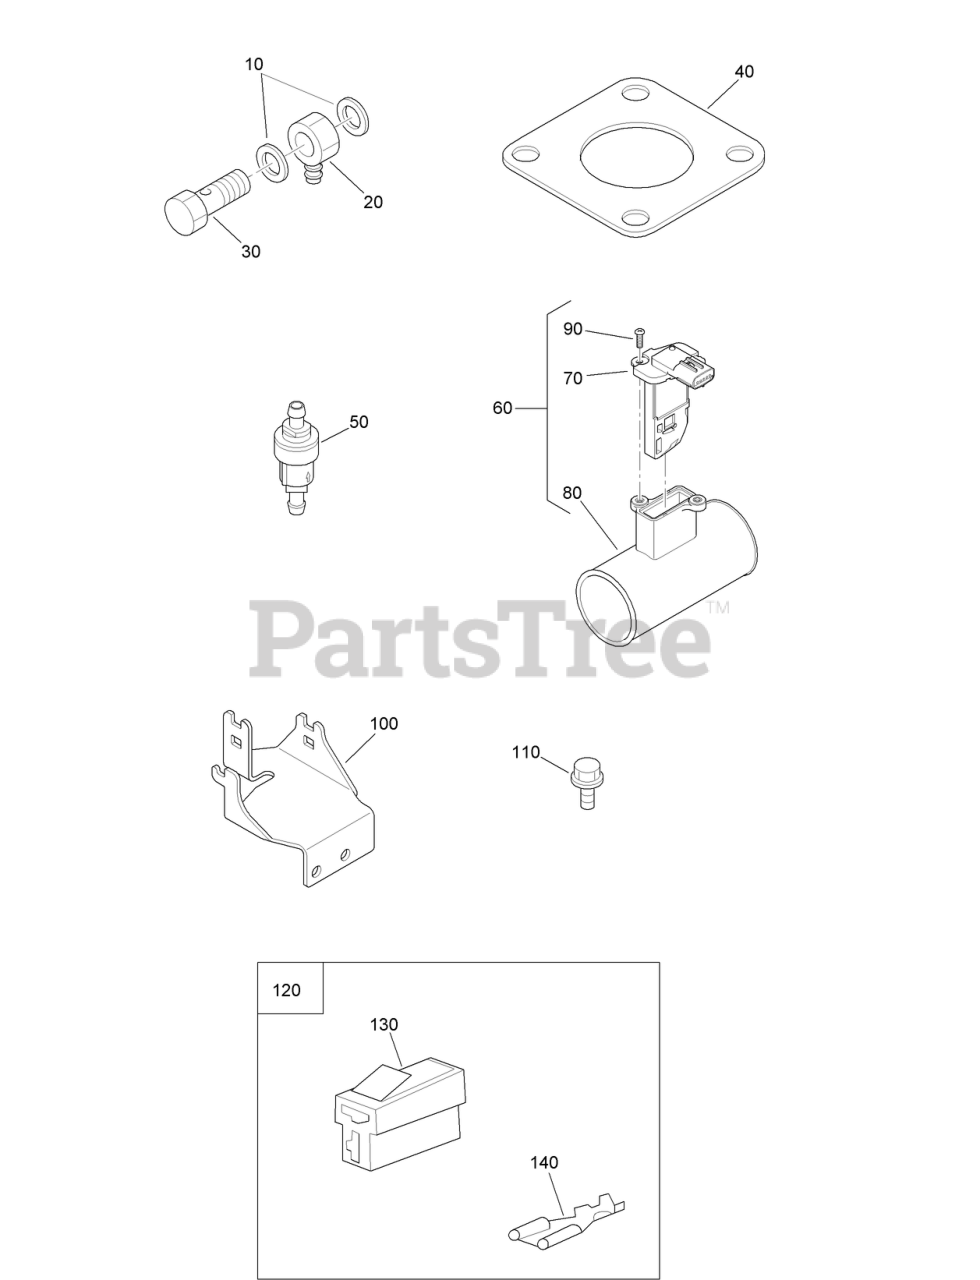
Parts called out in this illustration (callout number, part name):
10	O-RING
20	ADAPTER-FUEL
30	SCREW-ADAPTER
40	GASKET-MUFFLER
50	VALVE-CHECK, FUEL
60	SENSOR
70	SENSOR-FLOW, AIR
80	PIPE-FLOW, AIR
90	SCREW-PHILLIPS, PAN HEAD
100	BRACKET
110	BOLT-FLANGE
120	TERMINAL
130	COUPLER ASM
140	CONNECTOR
